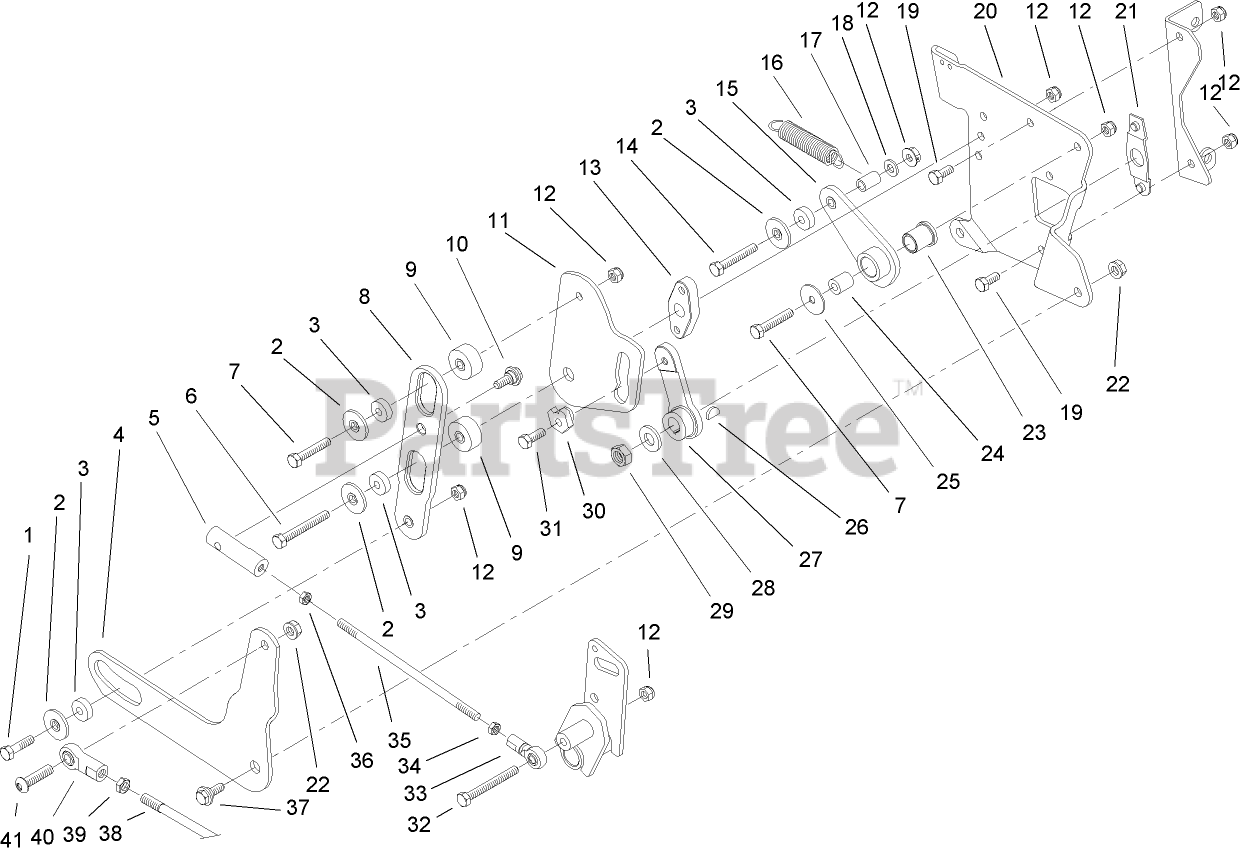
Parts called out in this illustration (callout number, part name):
1	SCREW-HH
2	RETAINER-BEARING
3	BEARING-BALL
4	SLIDER-LIFT
5	END-ROD, RH
6	SCREW-HH
7	SCREW-HH
8	SLIDER-CONTROL, SPEED
9	STANDOFF-CAM PLATE
10	BOLT-SHOULDER
11	PLATE-CAM
12	NUT-LOCK, NI
13	STANDOFF-SLIDER
14	SCREW-HH
15	ARM-RETURN TO NEUTRAL
16	SPRING-IDLER
17	STANDOFF-SPRING
18	WASHER-PLAIN
19	SCREW-HH
20	PLATE-CONTROL
21	LOCATOR-CONTROL PLATE
22	NUT-HEX
23	BUSHING-FLANGED
24	SPACER
25	WASHER-FLAT
26	KEY-WOODRUFF
27	ARM-CONTROL, SPEED
28	WASHER-FLAT
29	NUT-HEX
31	SCREW-THREAD LOCKING
32	SCREW-HH
33	END-ROD, RH
34	NUT-JAM
35	ROD-SLIDER TO PIVOT
36	NUT-JAM
37	BOLT-SHOULDER
38	ROD-LIFT
39	NUT-HJ
40	END-ROD, FEMALE
41	SCREW-HSBH
